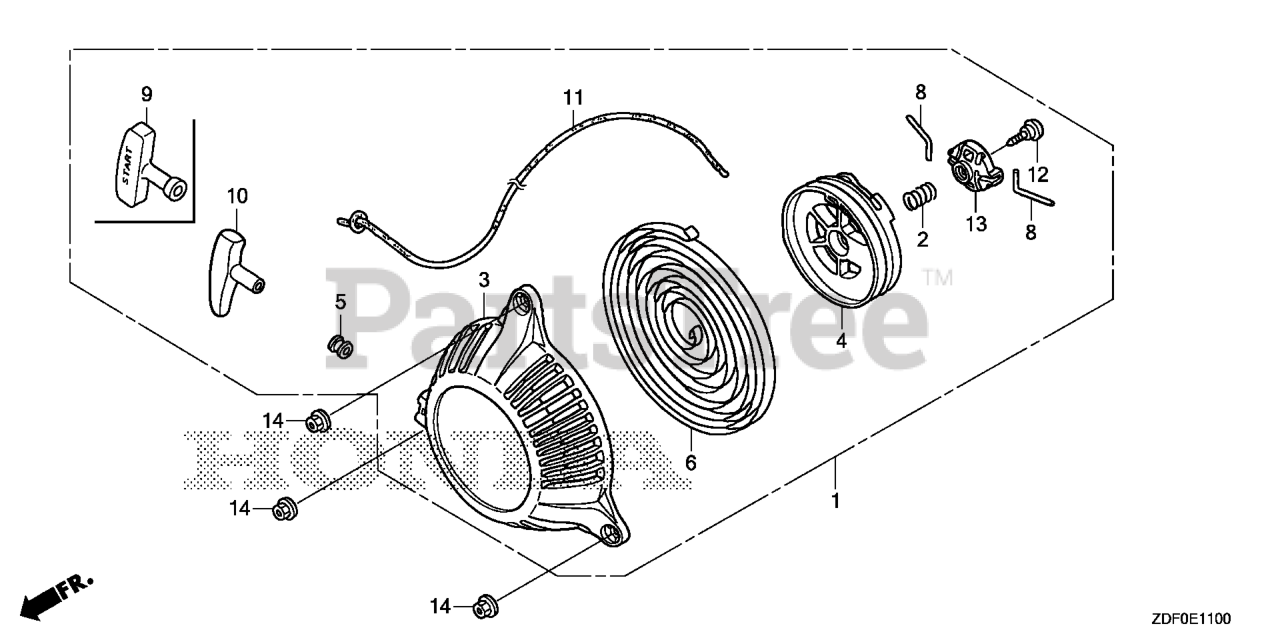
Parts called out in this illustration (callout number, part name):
1	STARTER ASSY., RECOIL
2	SPRING, FRICTION
3	CASE, RECOIL STARTER
4	REEL, RECOIL STARTER
5	GUIDE, ROPE
6	SPRING, RECOIL STARTER
10	KNOB, RECOIL STARTER
11	ROPE, RECOIL STARTER
12	SCREW, SETTING
14	NUT, FLANGE (5MM)
